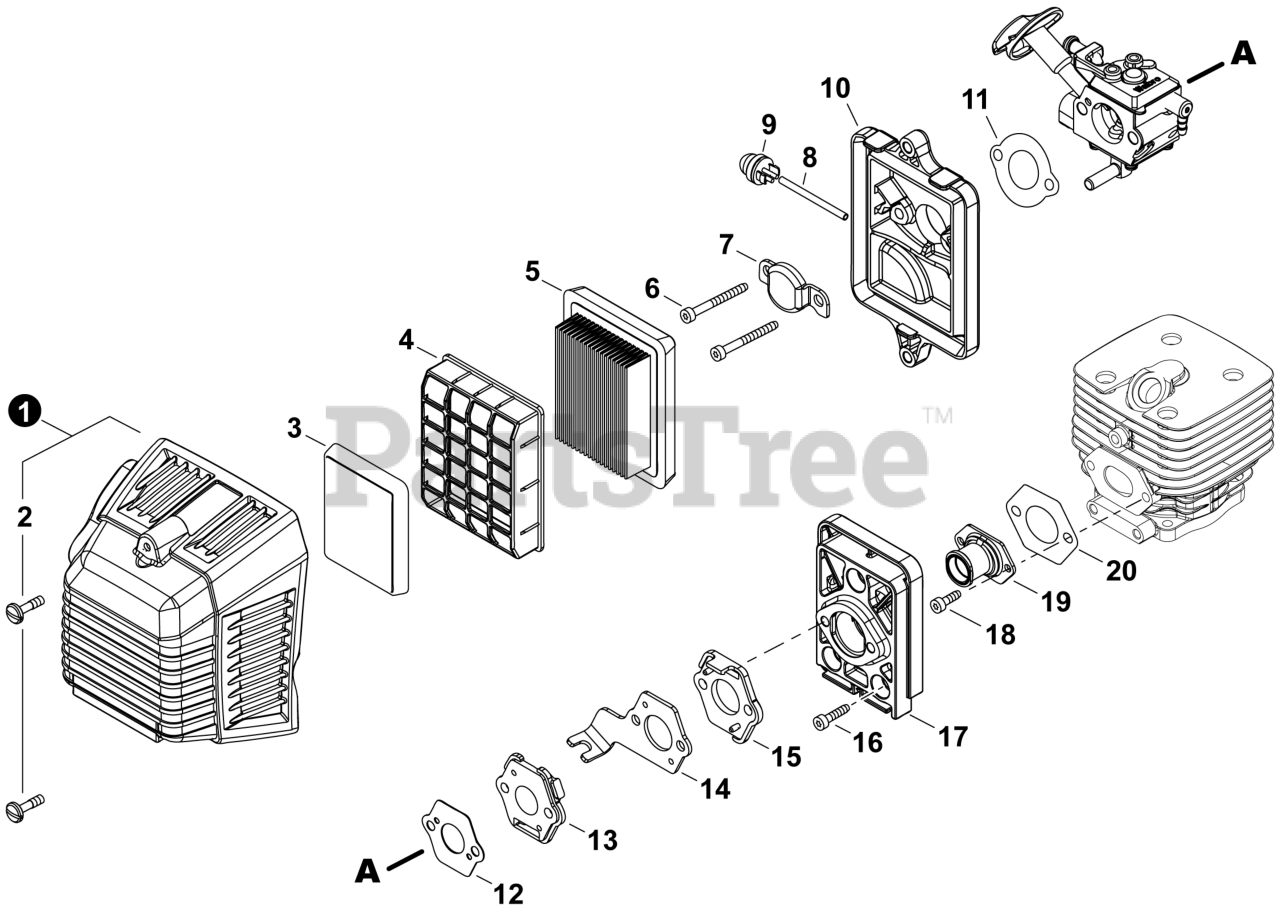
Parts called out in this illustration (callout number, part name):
1	COVER ASSY, AIR FILTER
2	SCREW 5x20
3	PRE-FILTER, FOAM
4	RETAINER, PRE-FILTER
5	FILTER, AIR
6	BOLT, TORX 5x65
7	PLATE, PREVENT
8	PIPE, FUEL 2.4x5x65 BLACK
9	BULB, PURGE
10	CASE ASSY, AIR FILTER
11	GASKET, INTAKE
12	GASKET, INTAKE
13	PLATE, INSULATOR
14	PLATE, SUPPORT
15	PLATE, INSULATOR
16	BOLT, TORX 5x20
17	INSULATOR, INTAKE
18	BOLT, TORX 5x12
19	BELLOWS, INTAKE
20	GASKET, INTAKE
